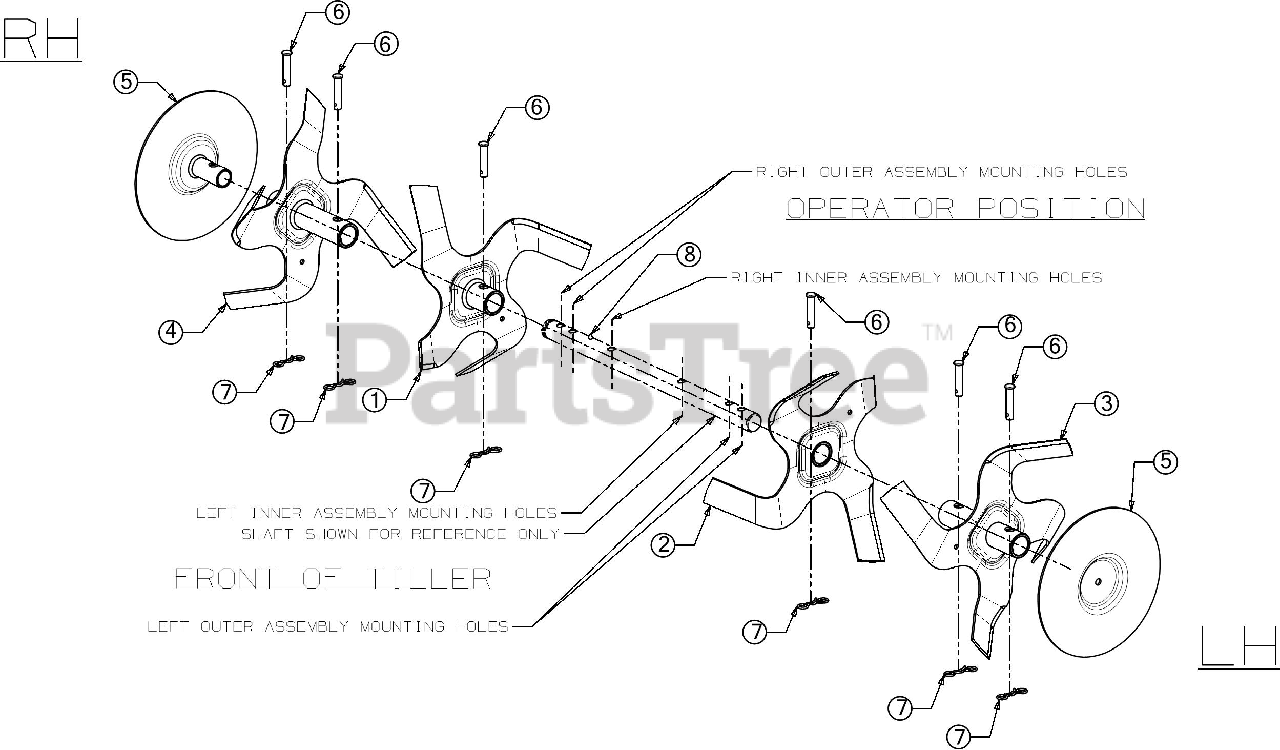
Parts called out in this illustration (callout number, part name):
1	TINE ASSEMBLY (INNER) (RH)
2	TINE ASSEMBLY (INNER) (LH)
3	TINE ASSEMBLY (OUTER) (LH)
4	TINE ASSEMBLY (OUTER) (RH)
5	OUTER DISC PLATE
6	CLEVIS PIN .375 X .1.75
7	PIN:COTTER
8	GREASE
